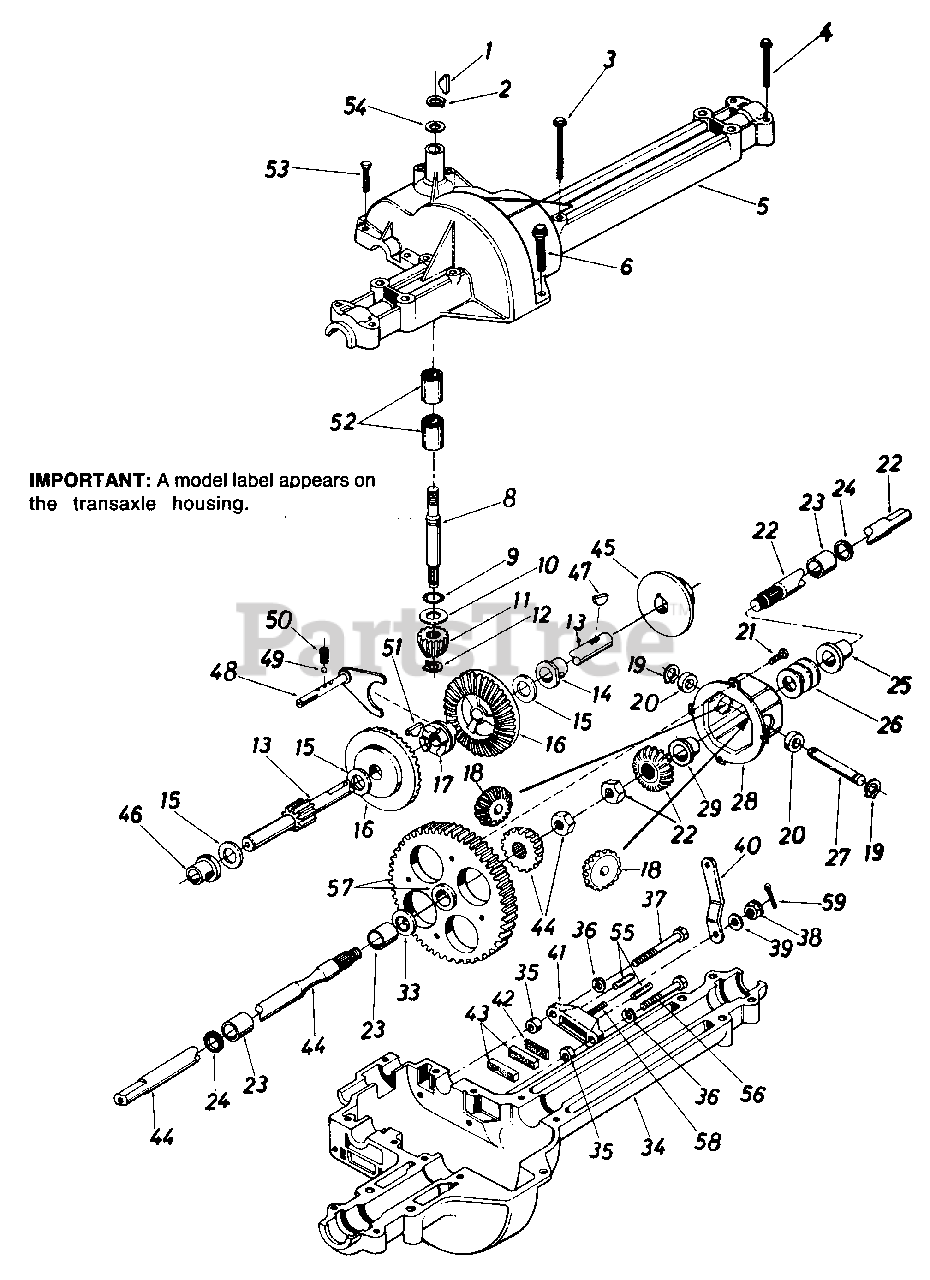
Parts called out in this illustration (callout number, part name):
1	#4 Hi-Pro Key 3/32 x 5/8" Dia.
2	Snap Ring .625" Shaft
3	Hex Bolt 1/4-20 x 1.75" Lg.
4	Hex Bolt 1/4-20 x 1.25" Lg.
5	Upper Housing
6	Hex Fl-Bolt 1/4-20 x .75" Lg.
8	Input Shaft
9	Square Seal 5/8" I.D.
10	Thrust Washer 5/8" I.D. x 1.25" O.D.
11	Pinion Input 14T
12	Retaining Ring 7/16" Ext.
13	Drive Shaft R.H.
14	Flange Brg. 5/8" I.D. x 3/4"
15	Fl-Wash.
16	Bevel Gear 42T
17	Clutch Collar
18	Miter Gear 15T
19	Retainer Ring
20	Thrust Bearing 1/2" I.D. x 1.0" O.D.
21	Pan Head Scr. 1/4-20 x .50" Lg. w/Patch
22	Axle R.H. Ass'y.
23	Sleeve Bearing 3/4" I.D. x 1.0" Lg.
24	Oil Seal 3/4" I.D.
25	Flange Bearing 3/4" I.D. x 15/16" Lg.
26	Fl-Wash. .760" I.D. x 1.49" O.D.
27	Cross Shaft
28	Differential Housing Ass'y.
33	Fl-Wash. .75" I.D. x 1.5" O.D.
34	Lower Housing
35	Spacer .53" O.D. x 3/8" Lg.
36	L-Wash. 1/4" I.D.
37	Hex Bolt 1/4-20 x 1.50" Lg. (Grade 5)
38	Castle Nut 5/16-24 Thd.
39	Fl-Wash. .34" I.D. x .875" O.D.
40	Actuating Arm R.H.
41	Brake Yoke
42	Puck Plate
43	Brake Puck
44	Axle L.H. Ass'y.
45	Brake Disc
46	Flange Bearing 5/8" I.D. x 15/16" Lg.
47	Woodruff Key 3/16 x 5/8 HT
48	Shift Fork Ass'y.
49	Ball Detent .250" Dia.
50	Spring Detent
51	#9 Hi-Pro Key 3/16" x 3/4" Dia. HT
52	Needle Brg. 5/8" I.D. x 1/2"
53	Hex Bolt 1/4-20 x 1 oon Lg
54	Fl-Wash. 5/8" I.D. x .030
55	Actuating Pin 5/16" Dia.
56	Hex Bolt 1/4-20 x 1.50" Lg. (Grade 5)
57	Differential Gear 72T Ass'y. w/Bearing
58	Sq. Hd. Bolt 5/16-24 Thd.
59	Cotter Pin 8132" Dia. x 1.0" Lg.
